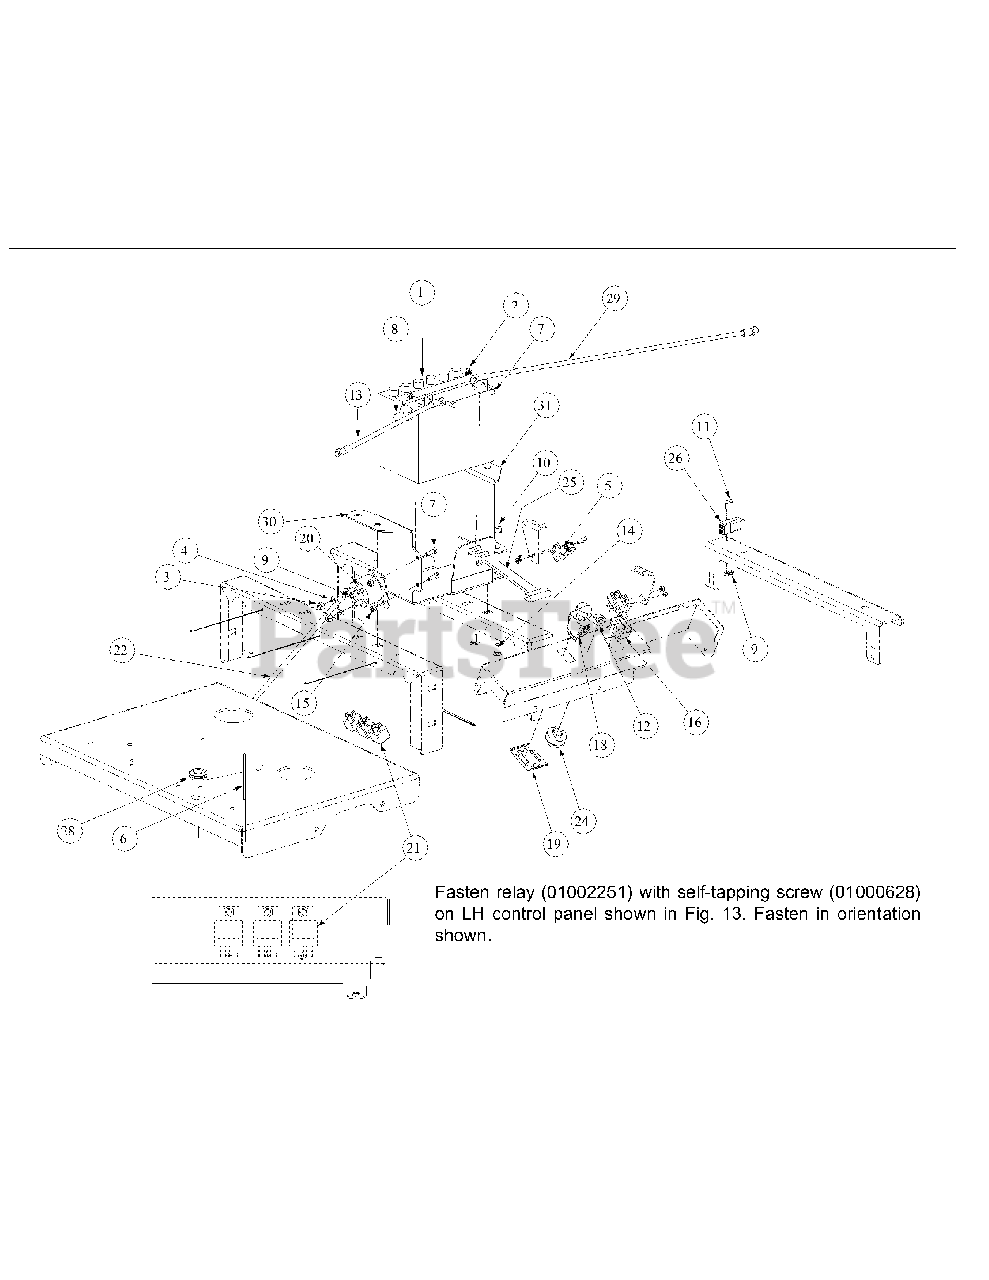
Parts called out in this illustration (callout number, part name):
1	Battery, 12V 225CCA 30 Min
2	Hex Flange Lock Nut, 1/4-20
3	Nylock Nut, 5/16-18
4	Lock Washer, 5/16
5	Switch, Safety N.O.\N.C.
6	Tie, Cable, 3/16 x .05 x 7.4"
7	Screw, Hex, Cap, 1/4-20 x .75
8	Boot, 1" OD Rubber Battery-PST, Red
9	Nut, Lock, Nylon Insert, #10-32
10	Nut, Hex, Flange Lock, 3/8-16
11	Screw, Phillips Head, Machine, 10-32 x 5/8
12	Nut, W/Cap, 5/8-32 Ignition
13	Cable, Battery, Red, 15"
14	Carriage Bolt, 3/8-16 x .75 LG.
15	Lock Nut w/Nylon Insert
16	Meter, Hour
18	Switch, Electric, PTO
19	Bracket, PTO Switch Retainer
20	Solenoid Magnetic Switch
21	Relay, 12V 40A
22	Cable, Battery Red, 32"
24	Switch, Ignition, 6 Pin
24	Key, Ignition
25	Strap, Battery
26	Switch, Plunger N.O.\N.O.
28	Grommet, .75 ID
29	Cable, Battery Black, 24"
30	Mount Bracket, Battery
31	Mount Bracket, Battery
